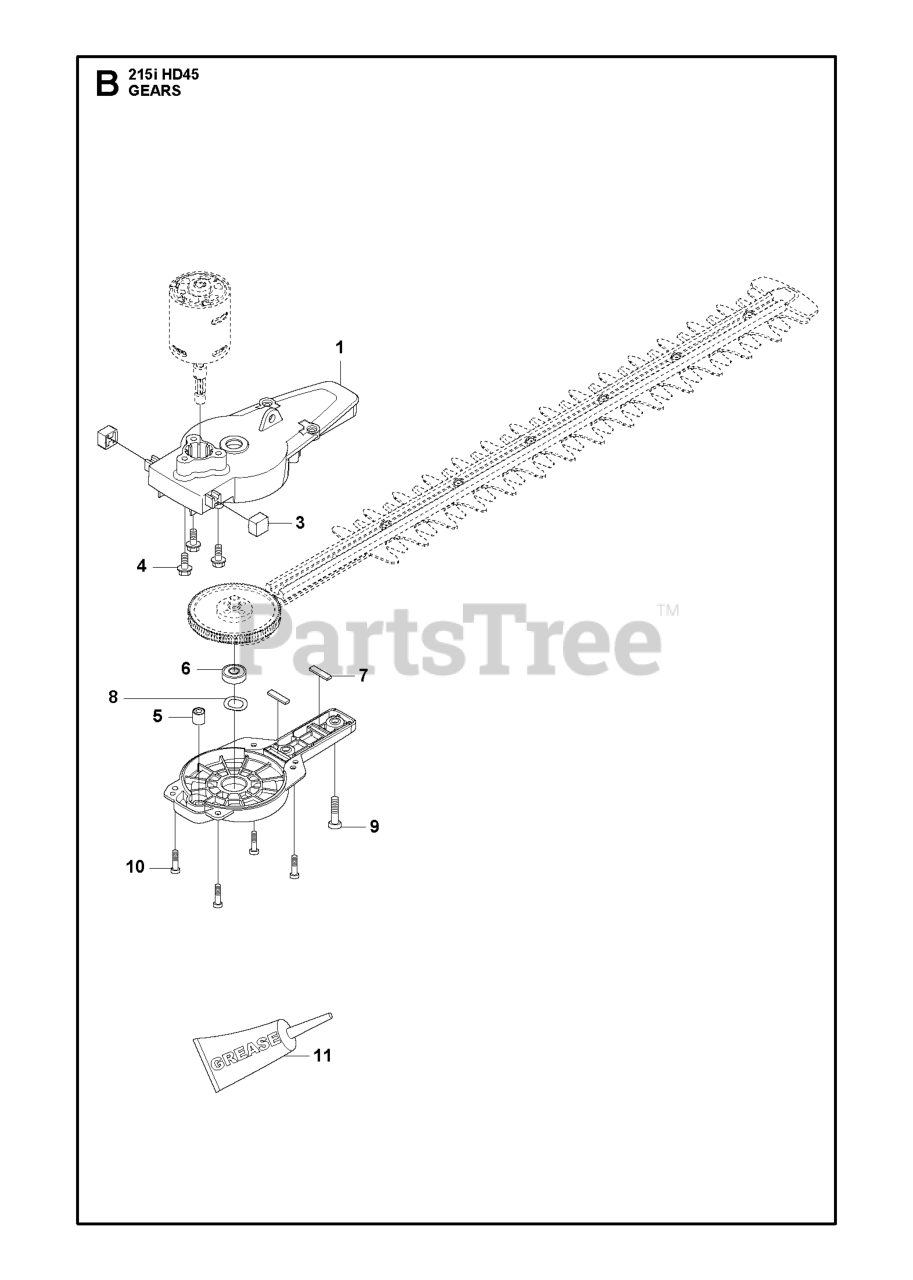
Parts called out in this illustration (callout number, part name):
2	COVER GEAR BOX
3	SHOCK ABSORBING
5	NEEDLE BEARING
6	BALL BEARING
7	PAD DUSTPROOF
8	SPRING WASHER
9	SCREW M5X20
10	SCREW M4X12
11	GREASE 20G HEDGE TRIMMER GEAR
